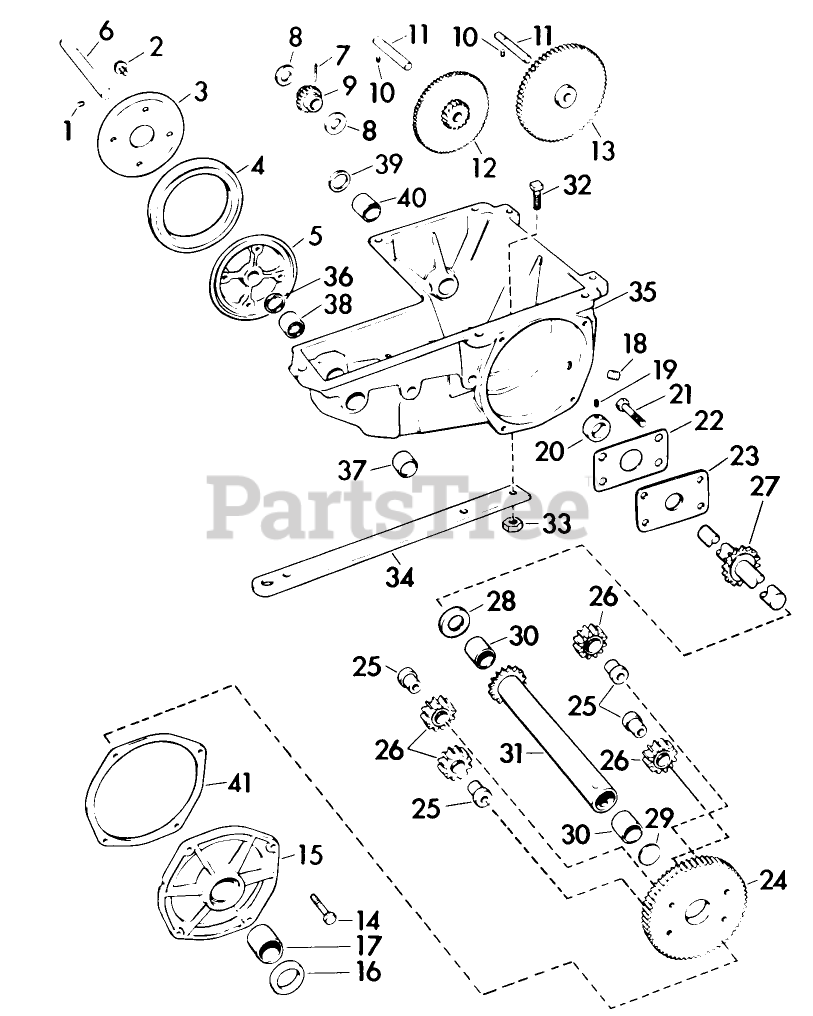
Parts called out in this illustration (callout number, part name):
10	SET SCREW
21	Screw-Differential
24	Gear-Reduction (No. 3)
26	Gear-Planet, Differential
34	Bar-Draw
